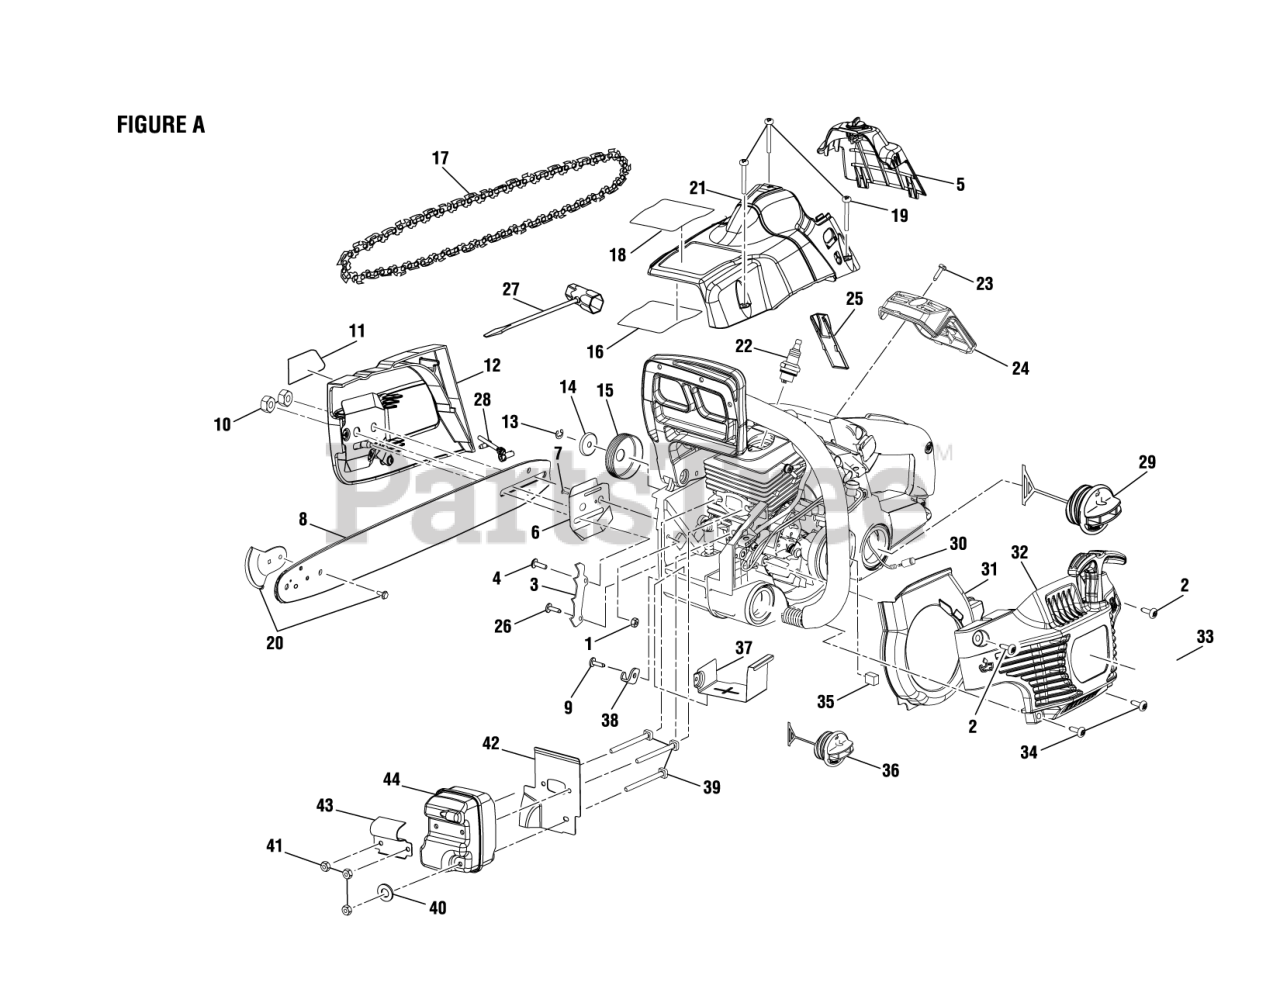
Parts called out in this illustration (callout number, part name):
1	NUT, LOCK
3	SPIKE, BAR
5	COVER, FILTER
6	PLATE, INNER GUIDE
8	20 in. Guide Bar
10	NUT, BAR (5/16-18)
11	LABEL, LOGO
12	ASSY., CHAIN COVER
14	HOSE, FUEL (RETURN)
15	ASSY., SPROKET DRUM
16	SHIELD, HEAT
17	Chain (.325 x 78 links, 20 in.)
18	LABEL, WARNING
20	KIT, SAFETY TIP & SCREW
21	COVER, ENGINE
22	PLUG, SPARK
24	FILTER, AIR
25	DIVIDER, CYLINDER HOUSING
27	WRENCH, COMBINATION
28	TENSIONER, CHAIN
29	ASSY., FUEL CAP
30	FILTER FUEL
31	BAFFLE, FAN HOUSING
32	ASSY., STARTER COVER
33	LABEL, LOGO
35	PREFILTER
36	ASSY., OIL CAP
37	SHIELD, HEAT
38	CATCHER, CHAIN
40	WASHER, RETAINING
41	NUT, LOCK
42	GASKET, MUFFLER
43	DEFLECTOR, MUFFLER
44	ASSY., MUFFLER
